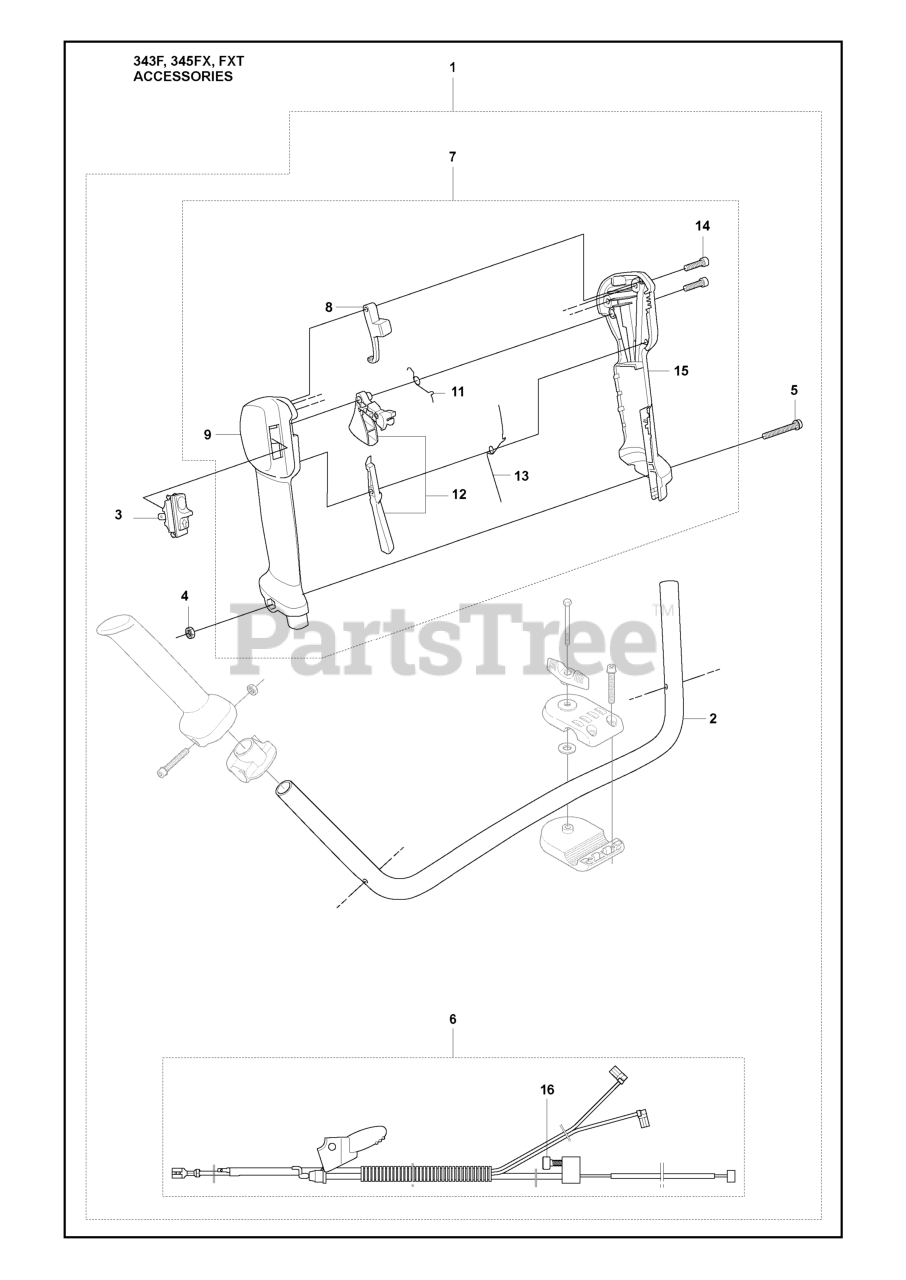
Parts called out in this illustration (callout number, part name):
2	HANDLE
5	SCREW
6	WIRING ASSY
7	THROTTLE HANDLE ASSY
8	LOCKOUT STARTER THROTTLE
9	HANDLE HALF LEFT
12	THROTTLE CONTROL
15	HANDLE HALF RIGHT
16	SCREW
